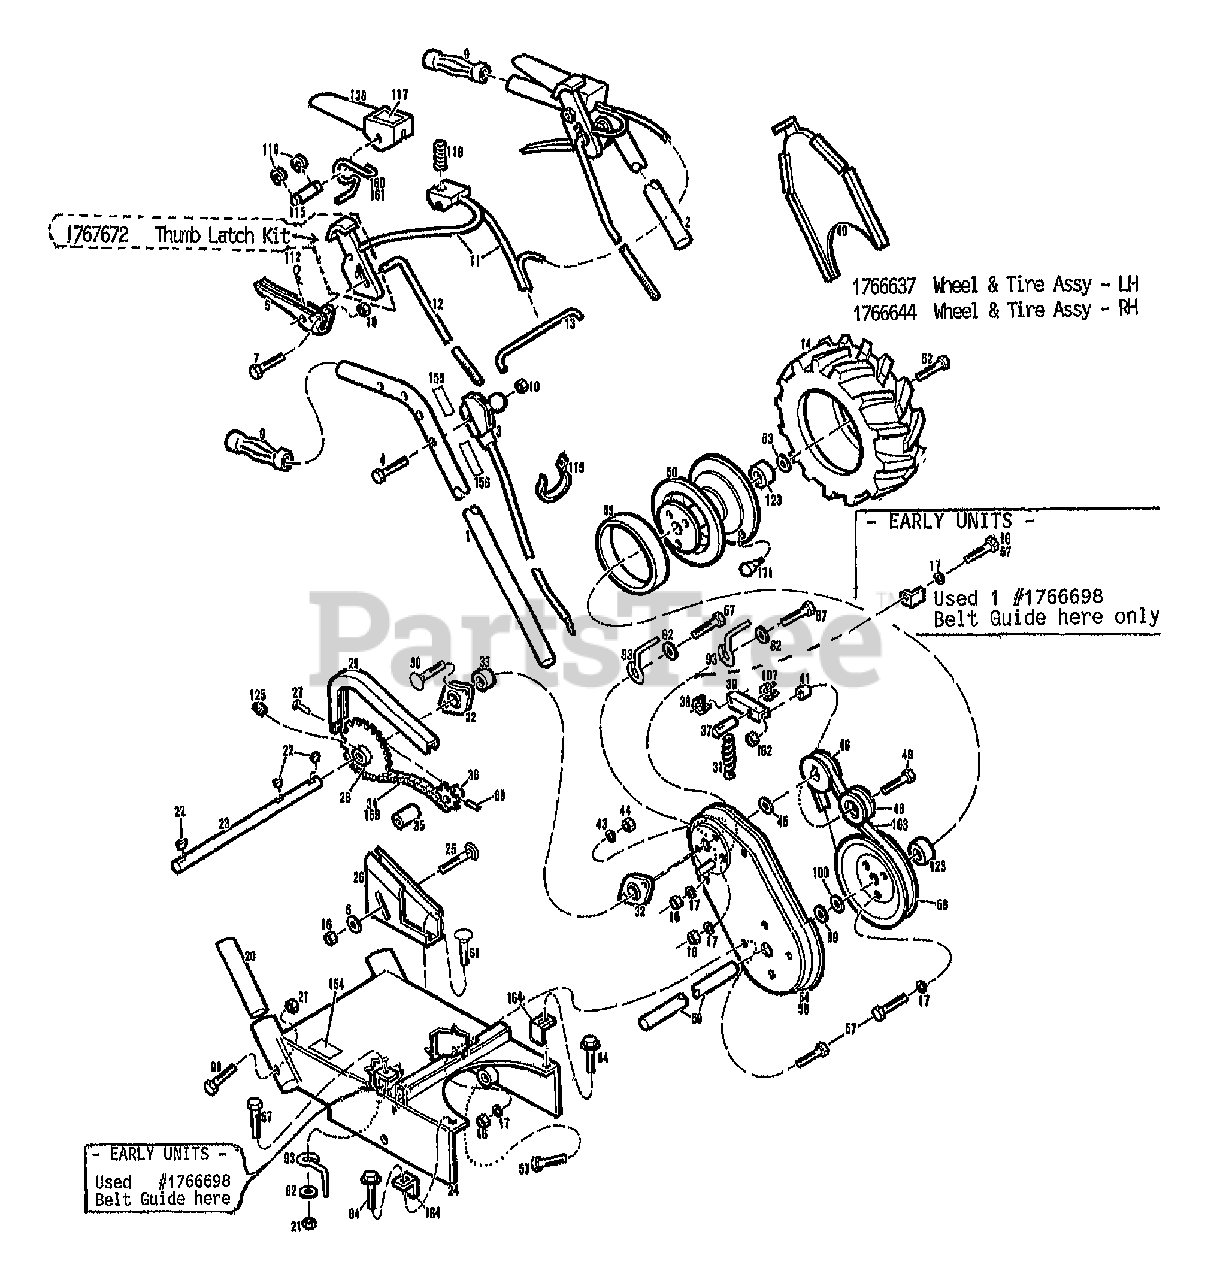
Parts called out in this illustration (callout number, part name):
1	HANDLEBAR-RH W/DECAL (INCL. 155 & 156)
2	HANDLEBAR-LH
3	ASSM-THROTTLE
4	SCR-HH 1/4-20X1.75 G5
5	LEVER-WHEEL CLUTCH
6	WASHER-FLAT 5/16 SAE
7	SCR-HH 1/4-20X1.5 G5
9	GRIP-FLEX
10	NUT-H/LK 1/4-20
11	HARNESS-OPERATOR INTERLK
12	ROD-WHEEL CLUTCH
13	BRIDGE-HANDLEBAR E-COAT
14	TIRE-LUG 13X5.00-6
16	NUT-HEX 5/16-18
17	WASHER-LK .312 INT TOOTH
20	ABSORBER-SHOCK
21	NUT-TOP/LK 5/16-18
22	KEY-WOODRUFF .188X.75
23	SHAFT-COUNTER
24	ASSM-ENGINE DECK PNT
25	SCR-CARR 5/16-18X1.25 G2
26	BRKT-CHAIN IDLER PNT
27	SCR-HW M10-24X.5 STH
28	SPROCKET-CHAIN 36T
29	COVER-CHAIN PNT
30	SCR-CARR 1/4-20X.50
31	CLUTCH-SPRING WHEEL
32	BEARING-RETAIN
33	INSERT-BEARING
34	CHAIN W/LINK
35	ROLLER-CHAIN IDLER
36	SPROCKET-CHAIN 12T
37	PIVOT-IDLER ARM
38	RING-RET."E" .300 ID
39	ARM-IDLER WHEEL CLUTCH
40	CVR-WHL/BELT GUARD PNT
41	SPACER-WHEEL IDLER
43	WASHER-LK .25
44	NUT-HEX 1/4-20
45	SPACER .625 ID
46	SHEAVE-COUNTER SHAFT
48	IDLER-FLAT
49	SCR-HH 3/8-16X2.25 G5
50	RIM-SICKLEBAR
52	SCR-HH 1/2-20X.75
53	WASHER-.94X.468X.065
54	ASSM-BELT GUARD LH
55	SPACER-WHEEL PULLEY PNT
56	SHEAVE-WHEEL
57	SCR-HHC 5/16-18X.75 GR 5
58	ASSM-BELT GUARD RH
59	AXLE-WHEEL
60	PIN-ROLL .188X1.0
61	SCR-CARR 5/16-18X.75
82	WASHER-FLAT 5/16 SAE
84	SCR-HFLK 5/16-18X.75
93	GUIDE-BELT
98	SCR-HH 5/16-18X2.25 G5
99	WASHER-BOW .75
100	THRUST WASHER
107	RING-RET."E" .437 ID
112	PIN-CLIP .08
115	PIN-PIVOT .25"
116	RING-CRESCENT EXT
117	DECAL-OPC CONTROLS
118	SPRING-COMPRESSION
119	TIE-CABLE NYLON BLACK
122	LOCTITE-242 (.5 ML TUBE)
123	BEARING-BALL
125	SCR-SET HX SOC HD 1/4-20
136	LEVER W/DECAL (INCL. 117)
154	DECAL-OIL DRAIN LOCATION
155	DECAL-THROTTLE
156	DECAL-PLACE HAN/PULL ROPE
160	SPRING-CONTROL LH
161	SPRING-CONTROL RH
162	NUT-H/LK 3/8-16
164	GUIDE-BELT
169	LINK-CHAIN CONNECTOR
170	PAINT-RED SPRAYCAN POWDER
171	STEM-VALVE
